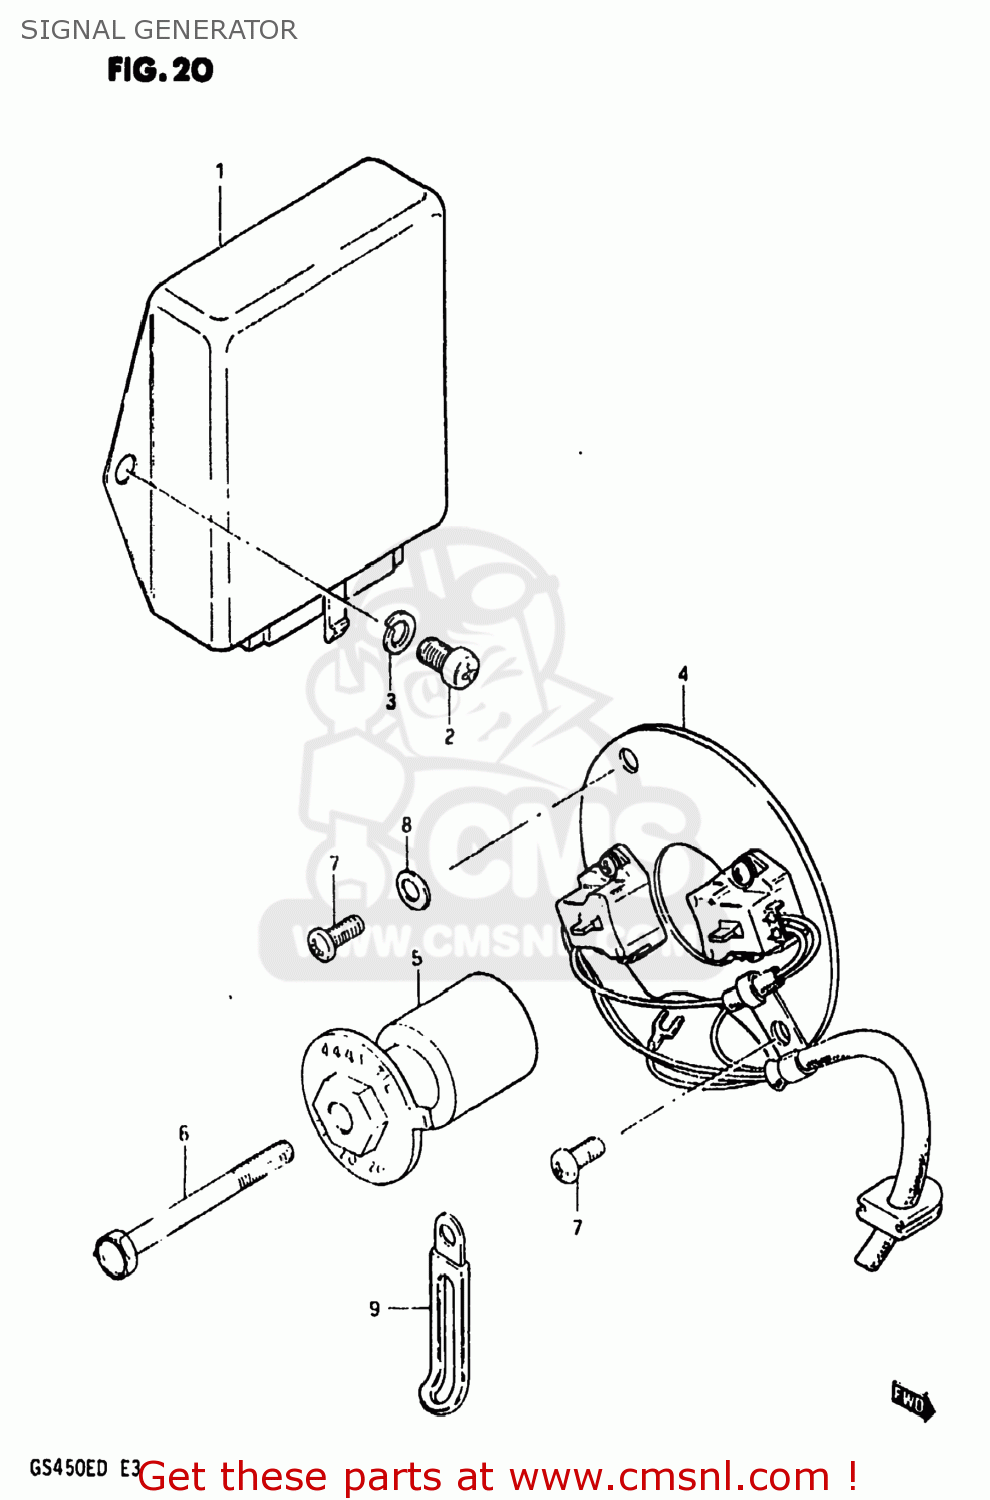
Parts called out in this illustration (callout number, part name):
1	IGNITOR UNIT
2	SCREW
3	LOCK WASHER
4	SIGNAL GENERATOR ASSEMBLY
5	ROTOR,SIGNAL
6	BOLT 6X60
7	SCREW(5X12)
8	WASHER
9	CLAMP L:35
